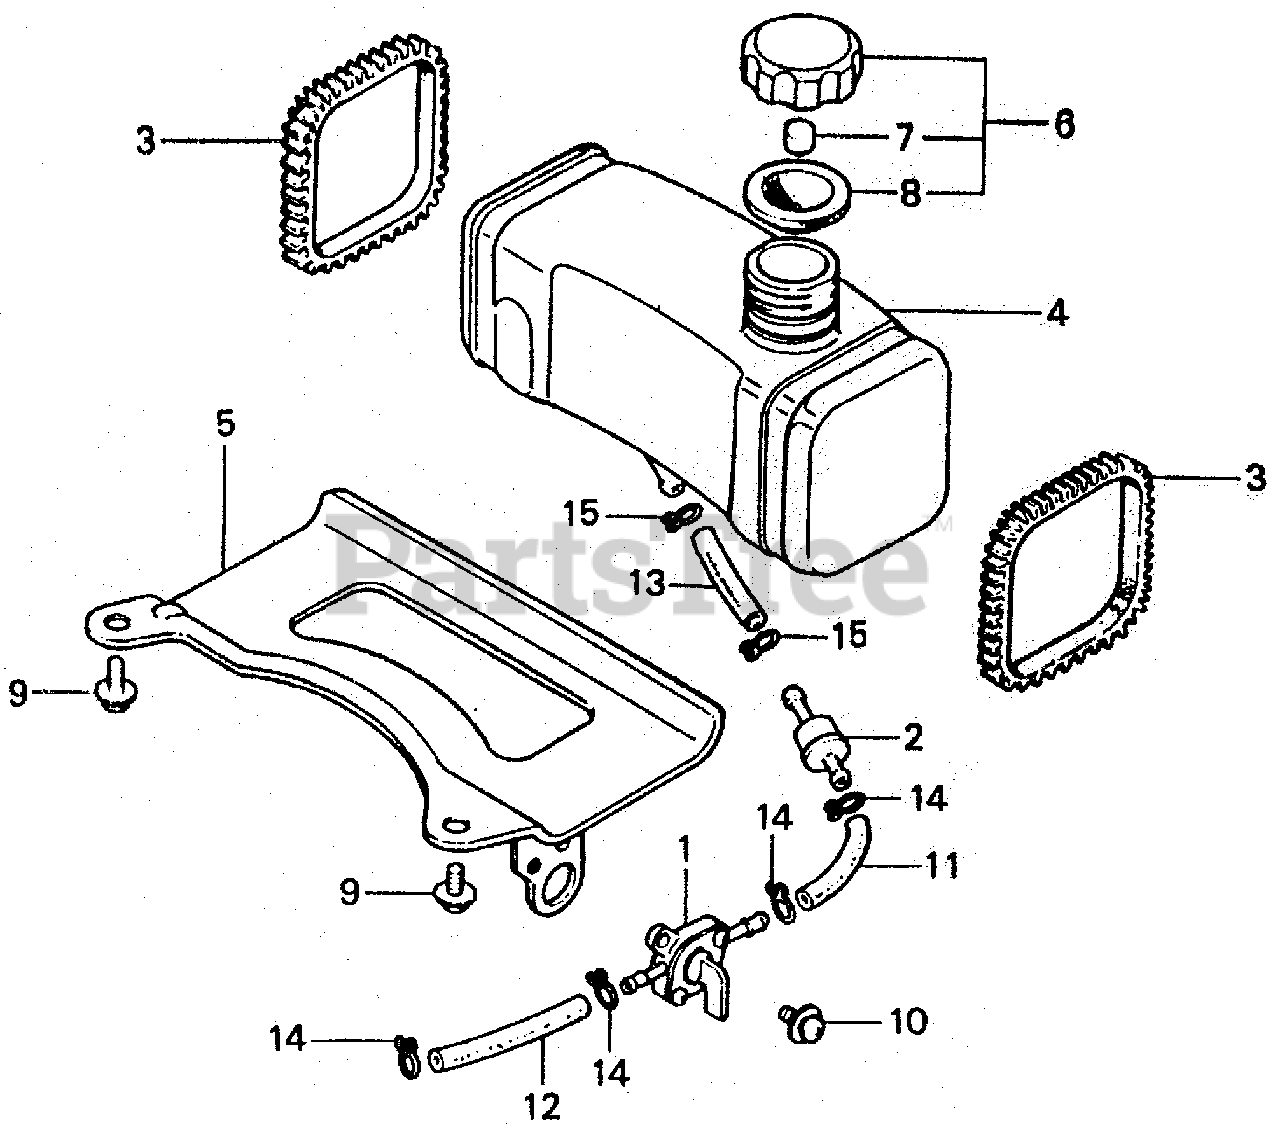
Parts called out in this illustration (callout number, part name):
1	PETCOCK ASSY.
2	FILTER, FUEL
3	CUSHION, FUEL TANK (NOT AVAILABLE)
4	TANK, FUEL (NOT AVAILABLE)
5	PLATE, TANK SETTING
6	CAP ASSY., FUEL TANK
6	CAP ASSY., FUEL TANK Use from Engine SN 2010636.
7	SPONGE, FUEL CAP BREATHER
8	GASKET, FUEL CAP
8	GASKET, FUEL CAP Use from Engine SN 2007016.
9	SCREW-WASHER (5X10)
10	SCREW-WASHER (5X12)
11	BULK HOSE, FUEL (4.5X3000) (Honda Code 5137104). (4.5X140)
12	BULK HOSE, FUEL (4.5X3000) (Honda Code 5137104). (4.5X140)
13	TUBE, FUEL
13	BULK HOSE, FUEL (5.5X3000) (Honda Code 5338587). (5.5X150)
14	CLIP, TUBE (B8)
15	CLIP, TUBE (B10)
